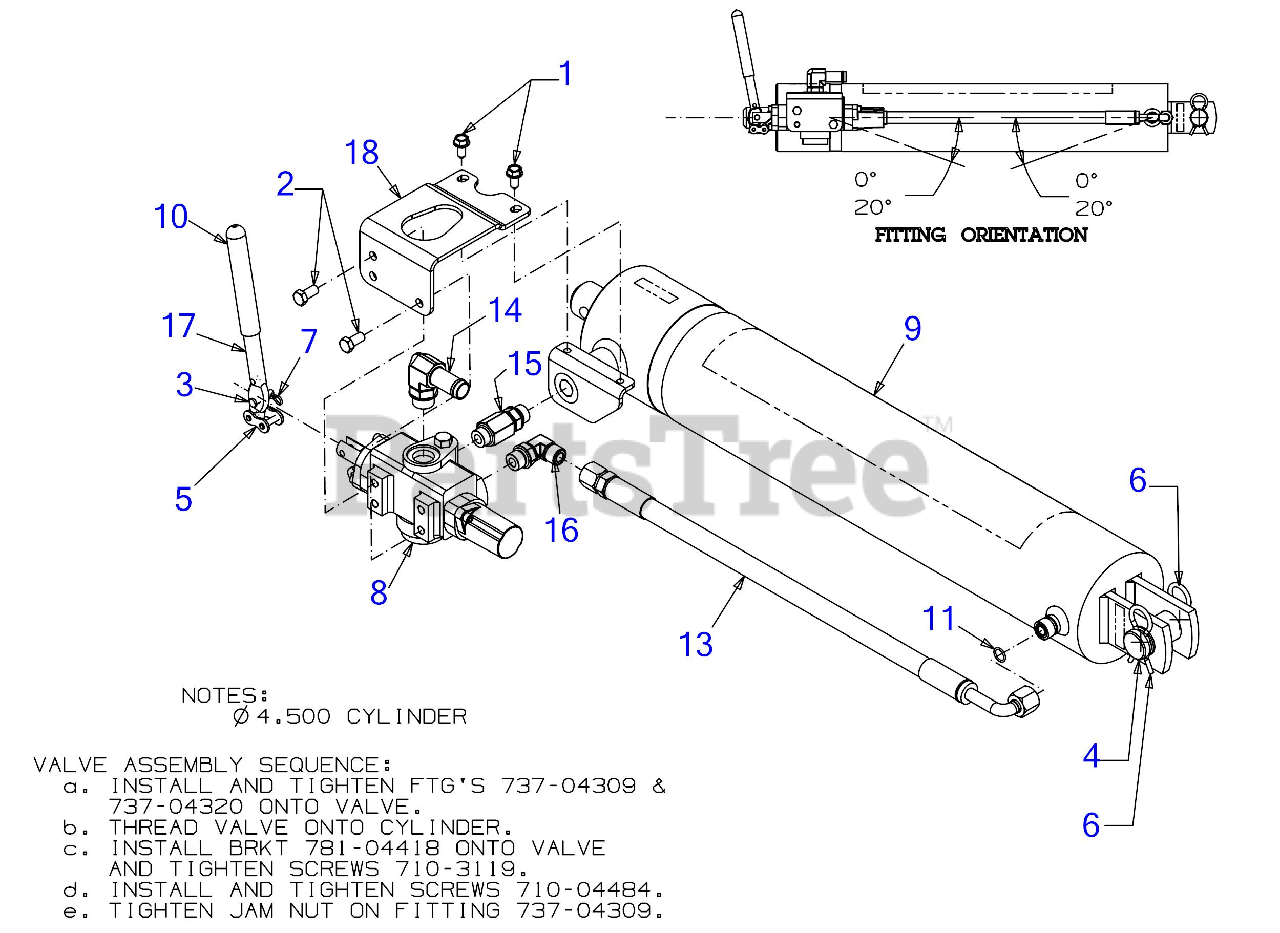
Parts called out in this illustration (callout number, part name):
1	SCREW 5/16-18 x .750
2	SCREW 3/8-16 x .75 GR 5
3	CLEVIS PIN .25 x 1.00
4	CYLINDER MOUTING PIN
5	VALVE HANDLE LINK
6	EXT COTTER PIN
7	BOW TIE COTTER PIN 1/4-5/16
8	LOGSPLITTER VALVE
9	HYDRAULIC CYLINDER 4.5 x 24
13	HYDRAULIC HOSE
14	HYDRAULIC FITTING
15	HYDRAULIC FITTING
16	HYDRAULIC FITTING
17	CONTROL VALVE HANDLE
18	VALVE BRACKET
